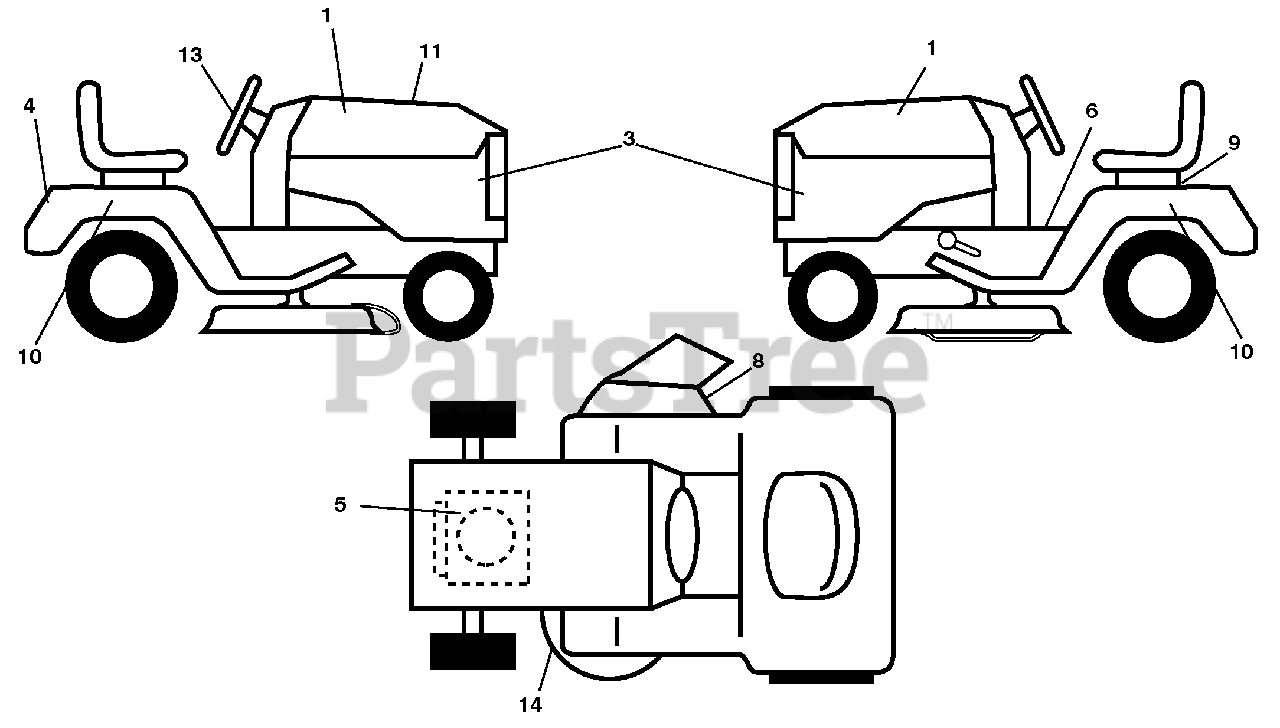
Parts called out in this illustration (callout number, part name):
1	Decal, Hood RH/LH
3	Decal, Side Panel
4	Decal, Fender
5	Decal, Eng H.P.
6	Decal, Fender Operator's
8	Decal, Warning
9	Decal, Battery Dnge/Poi
10	Decal, Fender SD RH/LH
11	Decal, Replacement
13	Decal, Steering Wheel
14	Decal, Mower Schematic
14	Pad, Footrest RH
14	Pad, Footrest, LH
14	Manual, Operator's (English/French)
14	Manual, Operator's (Spanish)
14	Manual, Parts (English/French)
